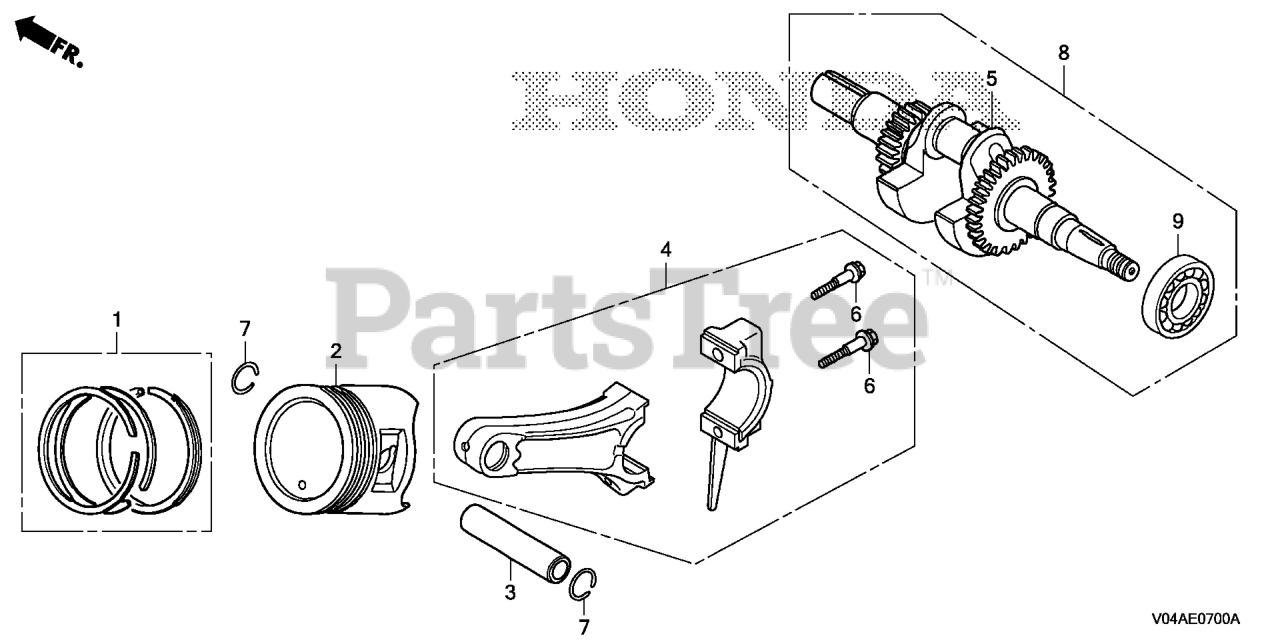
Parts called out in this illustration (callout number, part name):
1	RING SET, PISTON (STD) (TPR)
1	RING SET, PISTON (STD) (RIKEN)
2	PISTON (STD)
3	PIN, PISTON
4	ROD ASSY., CONNECTING
6	BOLT, CONNECTING ROD
7	CLIP, PISTON PIN (18MM)
8	CRANKSHAFT
9	BEARING, RADIAL BALL (6205)
9	BEARING, RADIAL BALL (6205) (NSK)
